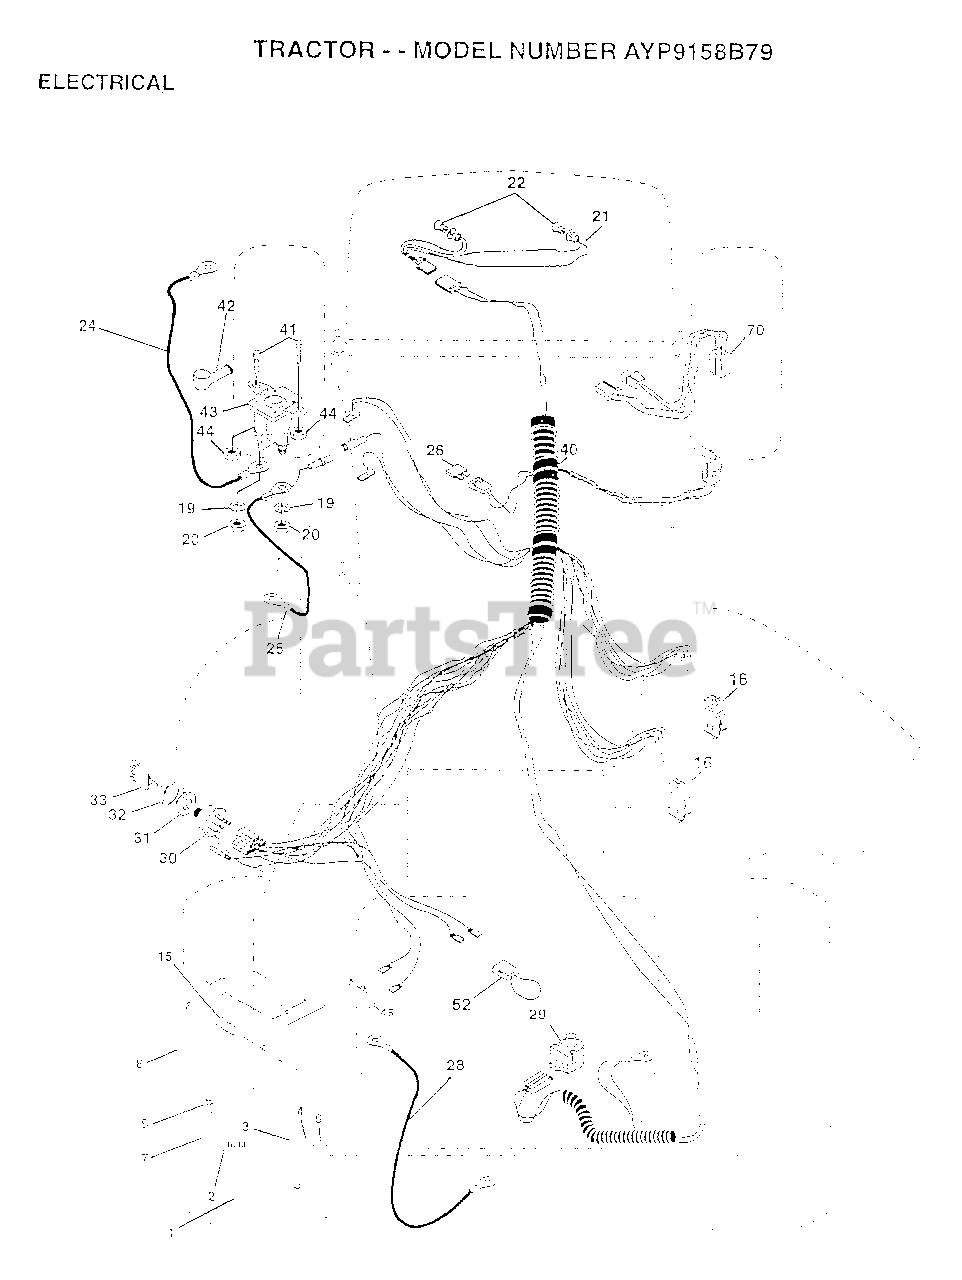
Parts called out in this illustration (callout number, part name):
2	BOLT LT
3	WASHER
4	LOCKWASHER
7	TUBE T
8	"CASE,BATTERY.MECH"
9	HOSE CLAMP T
15	FASTNER.SNAP-IN
16	SWITCH INTERLOCK
20	NUT
21	"HARNESS,LIGHT SOC"
22	HEADLAMP BULB
24	"CABLE T, BATTERY"
25	CABLE.BTRY.6GA.RD
26	FUSE HYT
28	CABLE T
29	SWITCH SEAT
30	SWITCH IGN 4POS
31	NUT IGNITION
32	COVER KEY SWITCH
33	KEY
40	HARNESS-IGNITION
41	BOLT HXHD FIN
44	NUT HXKEP 1/4X20
52	PROTECTION LOOP
70	HARNESS.ENG.DUAL
